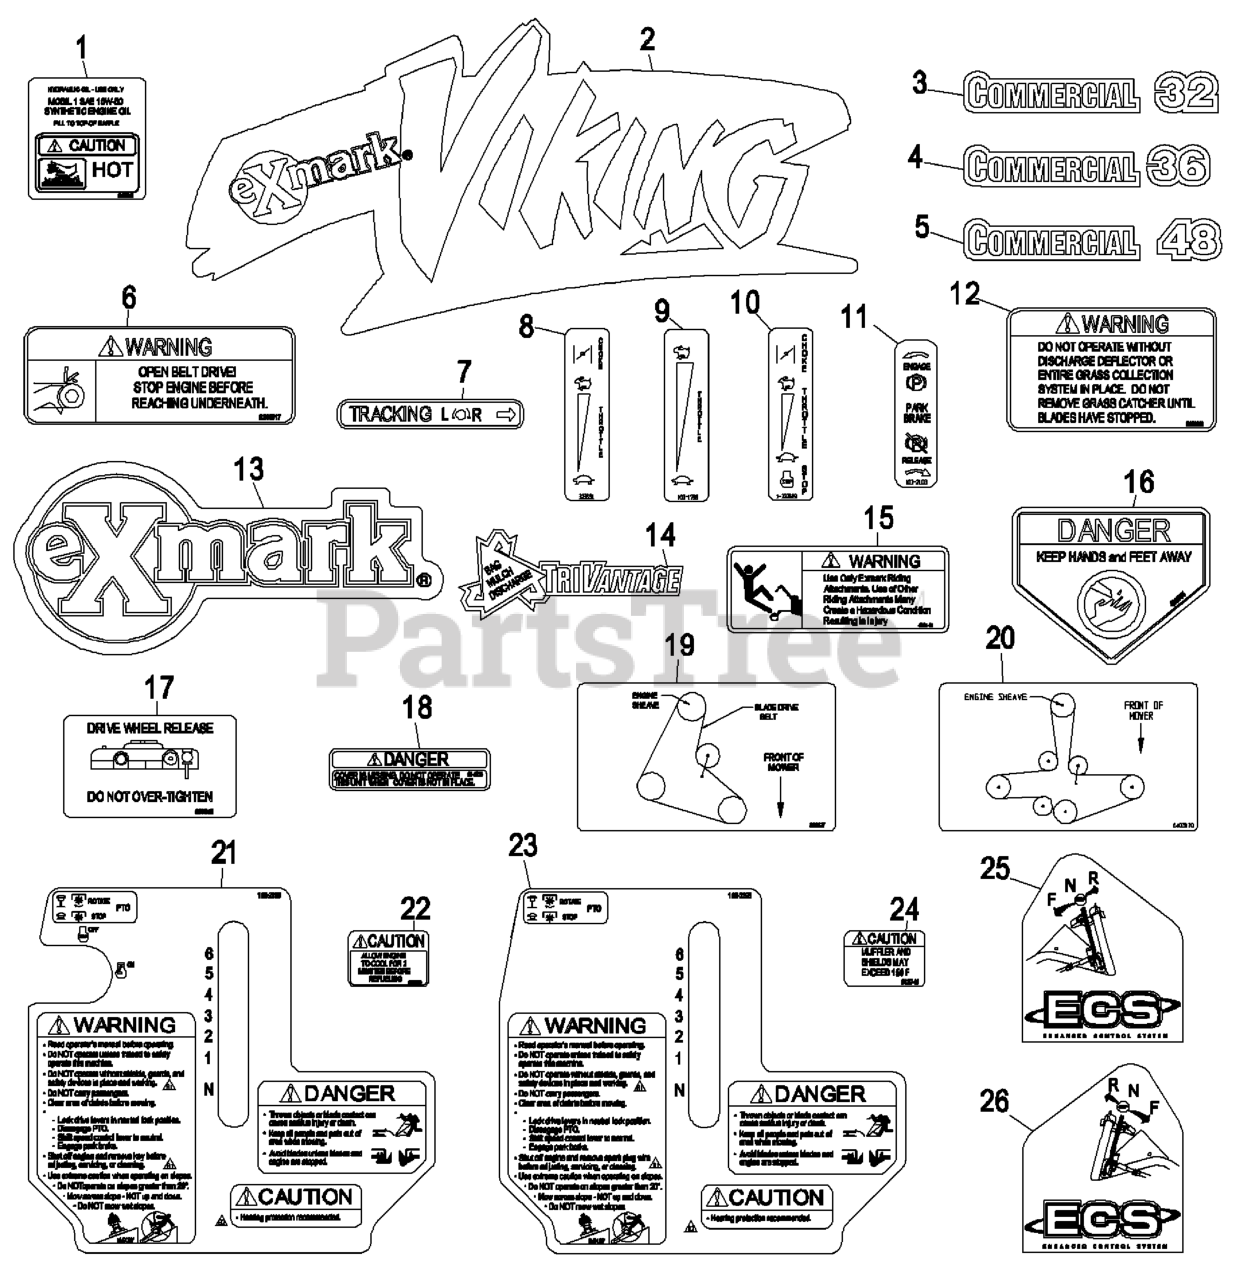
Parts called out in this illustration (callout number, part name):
3	DECAL,COMMERCIAL 32
4	DECAL,COMMERCIAL 36
5	DECAL,COMMERCIAL 48
6	DECAL,BELT DRIVE
8	DECAL,THROTTLE
9	DECAL,THROTTLE ONLY
11	DECAL-BRAKE, PARK
12	DECAL-WARNING, DISCHARGE
14	DECAL,TRACKING ADJUST
15	DECAL,SULKY WARNING
16	DECAL-DANGER
17	DECAL,DRIVE RELEASE
18	DECAL-COVER, MISSING
19	DECAL,BELT ROUTING 32/36
21	DECAL,CONSOLE VH ECS
23	DECAL,VH ECS KC CONSOLE
25	DECAL,LH ECS INSTRUCTION
26	DECAL,RH ECS INSTRUCTION
